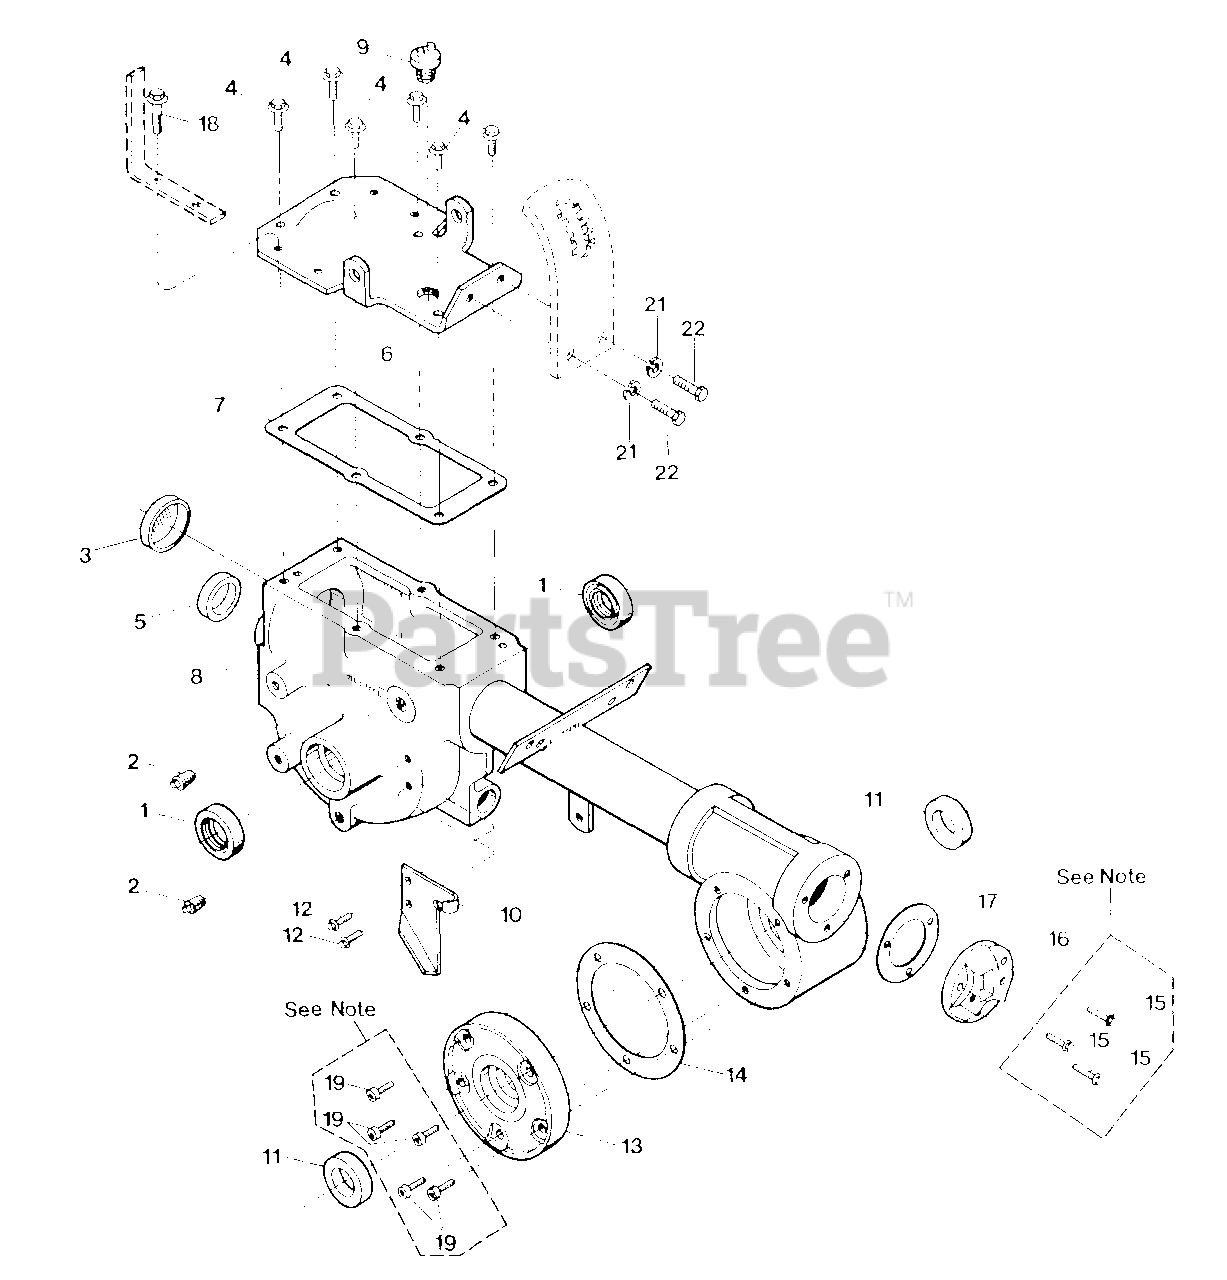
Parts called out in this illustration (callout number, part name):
1	Oil Seal-double lip, wheel shaft, right and left sides
2	Plug-pipe, 1/4, oil level hole and gear oil drain hole
3	Seal-transmission bore
4	Screw-flanged hex hd., 5/16-18 x 3/4
5	Oil Seal-input pinion shaft
6	Cover-top of transmission
7	Gasket-transmission top cover
8	Transmission case, tube and rear housing assembly
9	Plug-gear oil fill hole
10	Plate-wheel drive cable mounting.
11	Oil Seal-tiller shaft, left and right sides
12	Screw-flanged hex hd., 5/16-18 x 5/8
13	Cover-tiller housing, left side
14	Gasket-tiller housing cover, .010
15	Screw Kit
16	Cap-rear bearing
17	Gasket-rear bearing cap, .010 thick
18	Screw-flanged hex hd, 5/16-18 x 1
19	Screw Kit
21	Lockwasher-3/8
22	Screw-hex hd, 3/8-16 x 3/4
